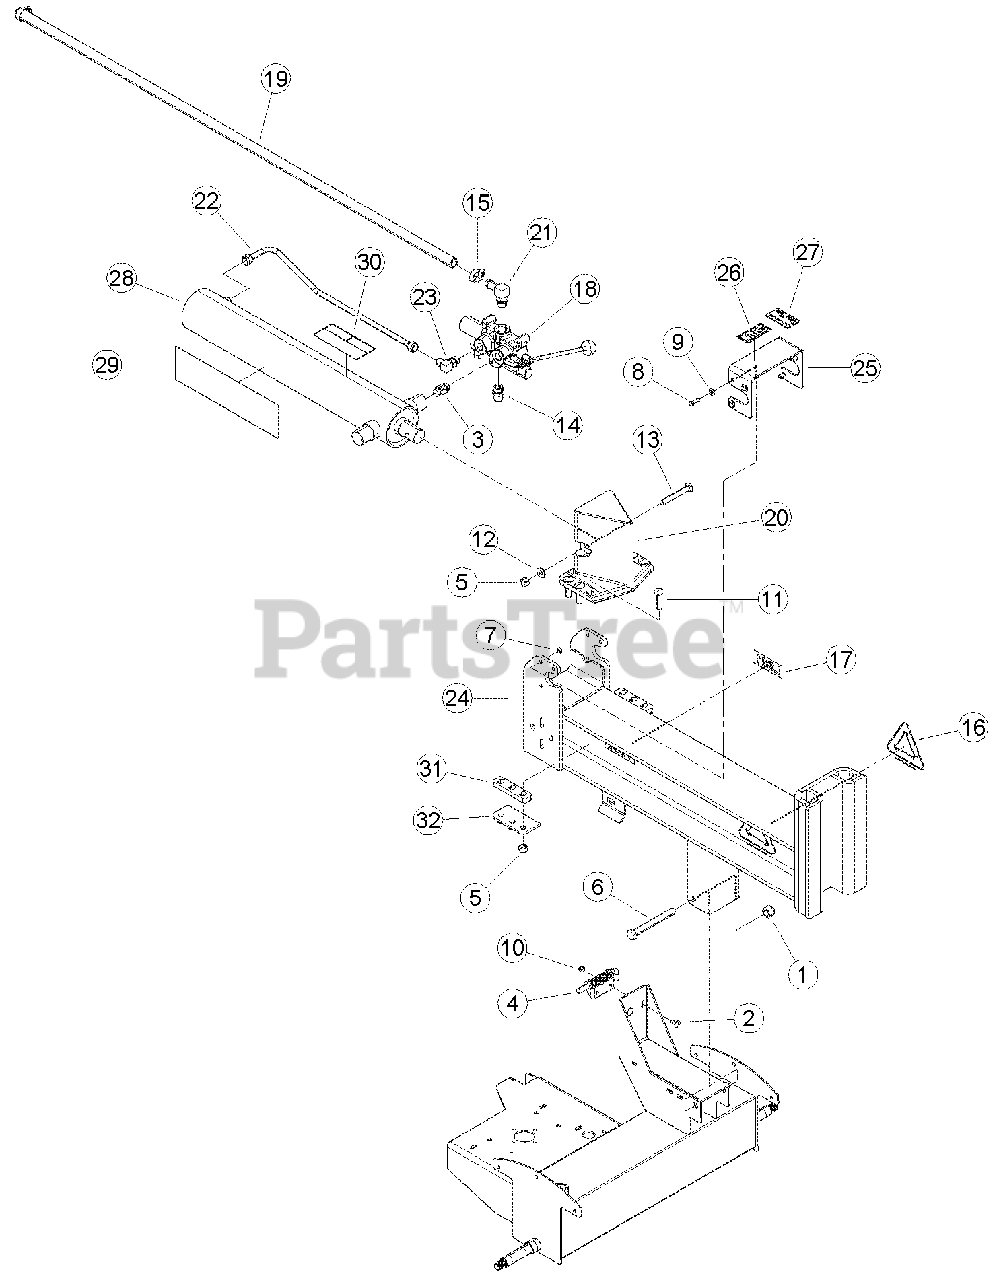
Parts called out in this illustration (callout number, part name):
1	NUT, 5/8-11 UNC NYLOCK
2	BOLT, 5/16-18 X 3/4 CRG GR5 SN
3	ADAPTER, -8 MORING / -8 MORING ADJ
4	LATCH, RH HINGE
5	NUT, 1/2 CENTERLOCK GRB ZP
6	BOLT, 5/8 X 5-1/2 HEX HD GR5 ZP
7	NUT 5/16 CENTERLOCK NC ZP
8	BOLT, 5/16 X 1 HEX HD GR5 NC ZP
9	WASHER, 5/16 FLAT ZP
10	NUT, 5/16 NE NYLOCK ZP
11	BOLT, 1/2 X 2 CRG GR5 ZP
12	WASHER, 1/2 HI-STRENGTH SAE ZP
13	BOLT, 1/2 X 4 CRG GR8
14	ADAPTER, -10 MORING / -10 MJIC
15	CLAMP, 1-1/4" HOSE
16	DECAL, RECLAIM IT
17	DECAL, MODEL LS27
18	VALVE, LOG SPLITTER
19	HOSE, 0.75 ID X 60" 100R4 HYD
20	WEDGE, CAST LOG SPLITTER
21	ADAPTER, -10 MORING/.75 90 DEG. HOSE
22	TUBE, HYDRAULIC
23	ADAPTER, -8 MORING / -8 MJIC 90 DEG.
24	WELDMENT, BEAM
25	CHANNEL, CRADLE CYLINDER, SERVICE PART
26	DECAL, CRUSHING ISO
27	DECAL, CYLINDER OPERATION (ISO)
28	CYLINDER, WELDED 4.50 X 24.00, SERVICE PART
29	DECAL, ECHO BEARCAT 14.12 X 4.00
30	DECAL, MUTILINGUAL MANUAL
31	PLATE, BOTTOM WEDGE
32	PLATE, CAST WEDGE BOTTOM
